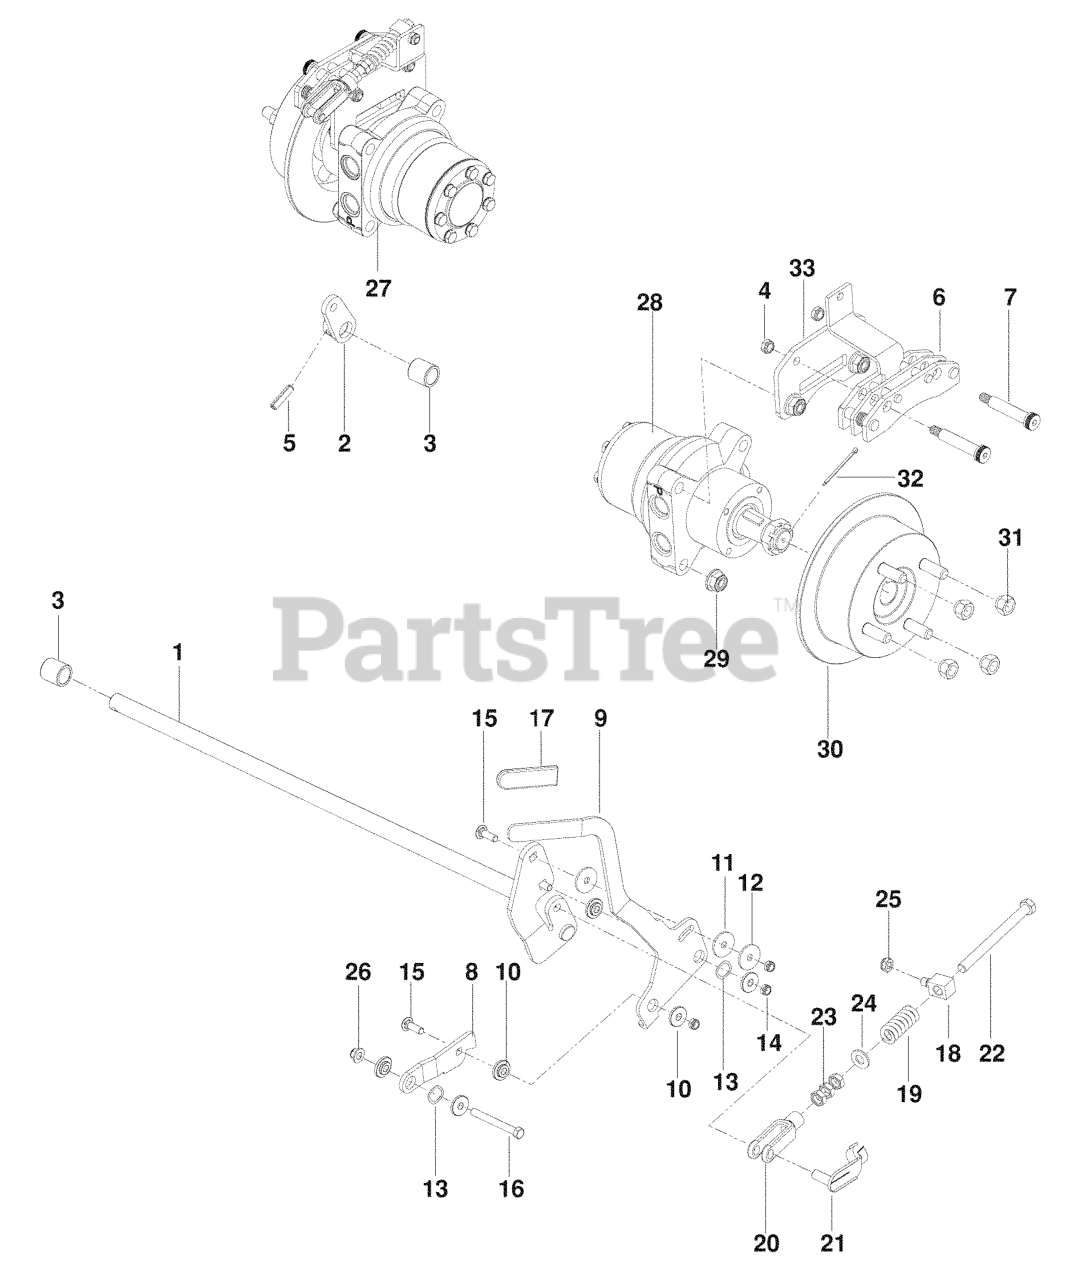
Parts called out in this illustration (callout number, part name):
1	SHAFT, BRAKE WLDMT
2	ARM, RT BRAKE
3	BUSHING, SLEEVE 3/4 X 1.0
4	NUT HEX 3/8-16 NYLON, THIN
5	5/16 DIA ROLL PIN
7	BOLT, SHOULDER, 1/2 X 2.25
8	LINK, FOLLOWER
9	LEVER.BRAKE.BLACK
10	BUSHING, BRAKE
11	WASHER, FRICTION, 1/8
12	CONE WASHER
13	WASHER, .825 X 1.087, WAVE
14	NUT HEX 3/8-16 NYLON, THIN
15	RHSNB 3/8-16 X 1-1/4
16	HCS 3/8-16 X 3-1/4 GR5 ZD
18	SWIVEL, BRAKE
20	YOKE-3/8-24 PLTD
21	PIN, CLEVIS SPRING, 3/8
22	HCS 3/8F X SPECIAL
23	NUT 3/8-24 JAM
24	WASHER 3/8 SAE FLAT
25	5/16-18 THIN PROF NY
26	NUT 3/8-16 HEX FLG NYLOC ZD
27	MOTOR, TL0310, RT
28	MOTOR, TL0310, LT
29	NUT, 1/2-13 HEX FLG NYLOC ZD
30	HUB, DISC BRAKE, W/STUDS
31	LUG NUT 1/2F
32	COTTER PIN 1/8 X 2
33	PLATE, CALIPER
